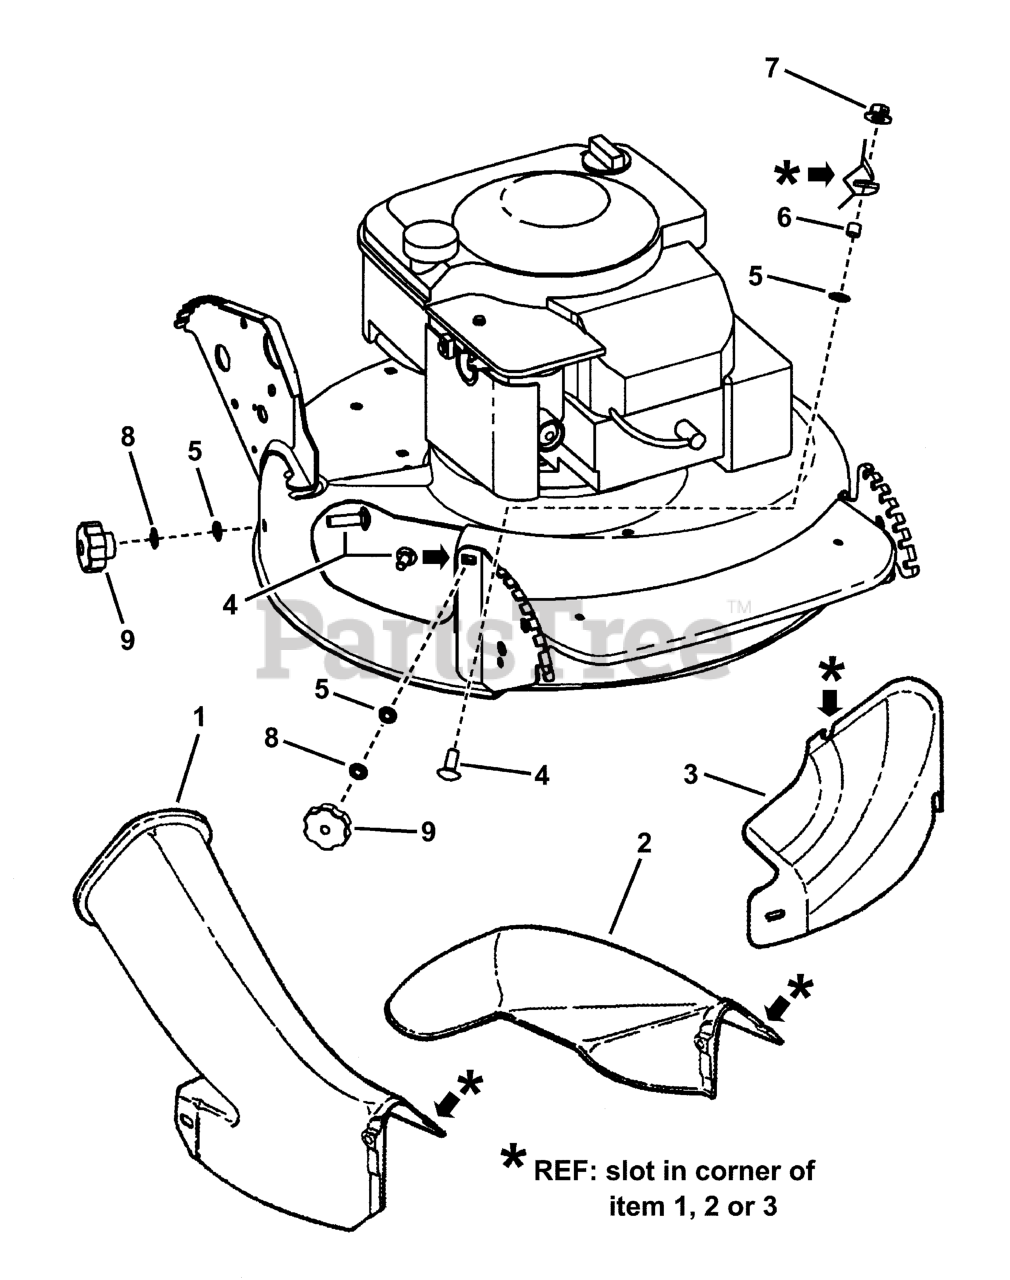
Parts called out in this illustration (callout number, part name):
1	ADAPTER, Grass Bag
2	CHUTE, 21" Side
3	COVER, 21" Deck
4	BOLT, 5/16-18 x 3/4" Short Neck Carriage GR 5
5	RETAINER, 5/16" Bolt
6	SPACER, .316 I.D. x .375 O.D. x .310 thick
7	NUT, 5/16-18 Hex Large Flange Center Lock
8	WASHER, 5/16" Internal/External Tooth Lock
9	KNOB, Fluted, 5/16-18 x .633
